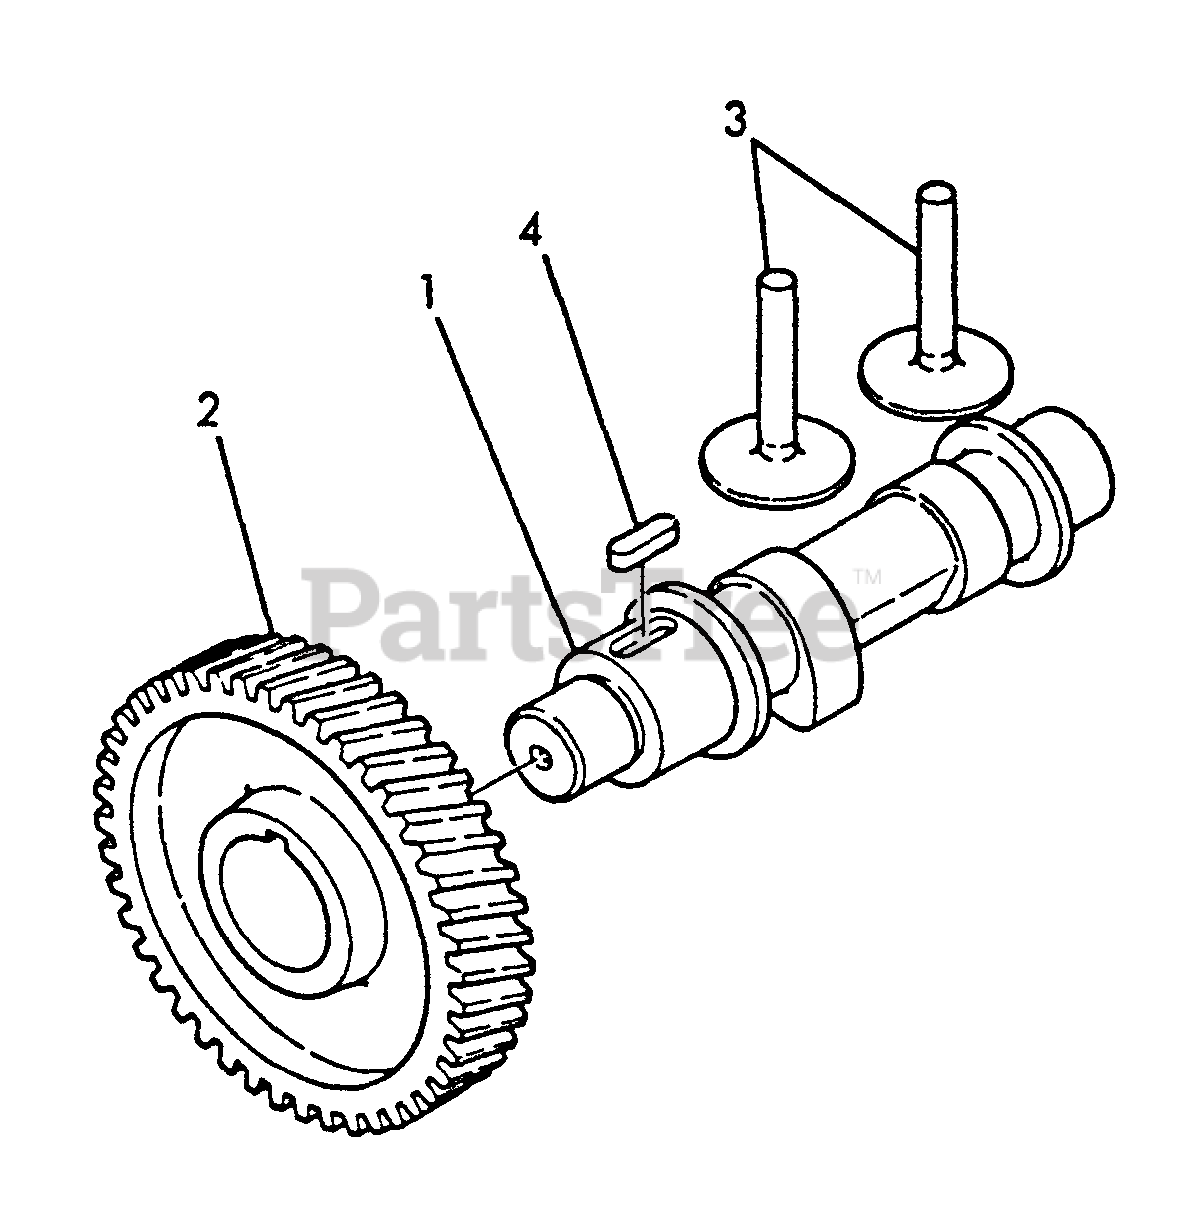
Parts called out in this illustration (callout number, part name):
1	CAMSHAFT
2	GEAR, CAMSHAFT
3	TAPPET
4	FEATHER KEY 5 X 16
